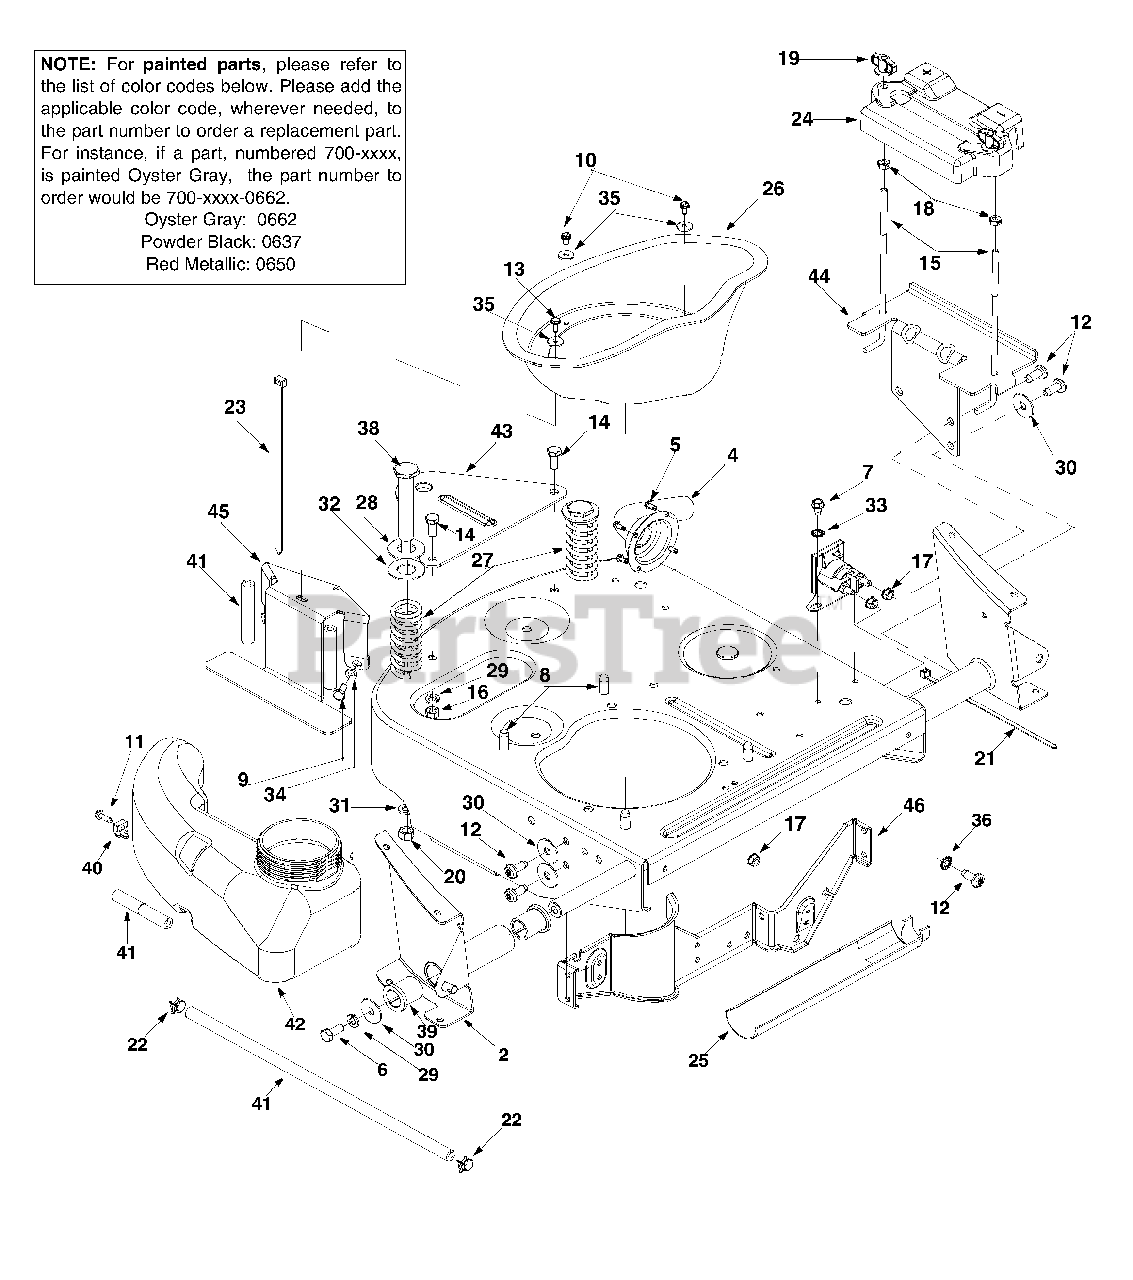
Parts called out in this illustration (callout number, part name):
5	Hex Fl. Screw #8-32 x 0.375
6	Hex Screw 5/16-24 x .75" Gr.5
7	Self-Tapping Screw
8	TT Screw 3/8-16 x 1.0"
9	Hex Screw 1/4-20 x 0.5"
10	Hex Slot Sems Screw #10-32 x 0.38
11	TT Screw #10-32 x 0.625"
12	TT Screw 5/16-18 x 0.75"
13	Machine Screw #10-32 x 0.5"
14	Hex Screw 5/16-18 x 0.75"
15	Battery Hold-Down Rod
16	Hex Nut 5/16-18
17	Hex Sems Nut 1/4-20
18	Lock Nut 1/4-20
19	Wing Nut with Bell Washer
23	Cable Tie
24	Battery Cover
25	Oil Drain Sleeve
27	Compression Spring
28	Rubber Washer
29	Lock Washer
30	Flat Washer
34	Lock Washer
38	Shoulder Screw
39	Flange Bearing
40	Throttle Casing Clamp
41	Fuel Line Hose
